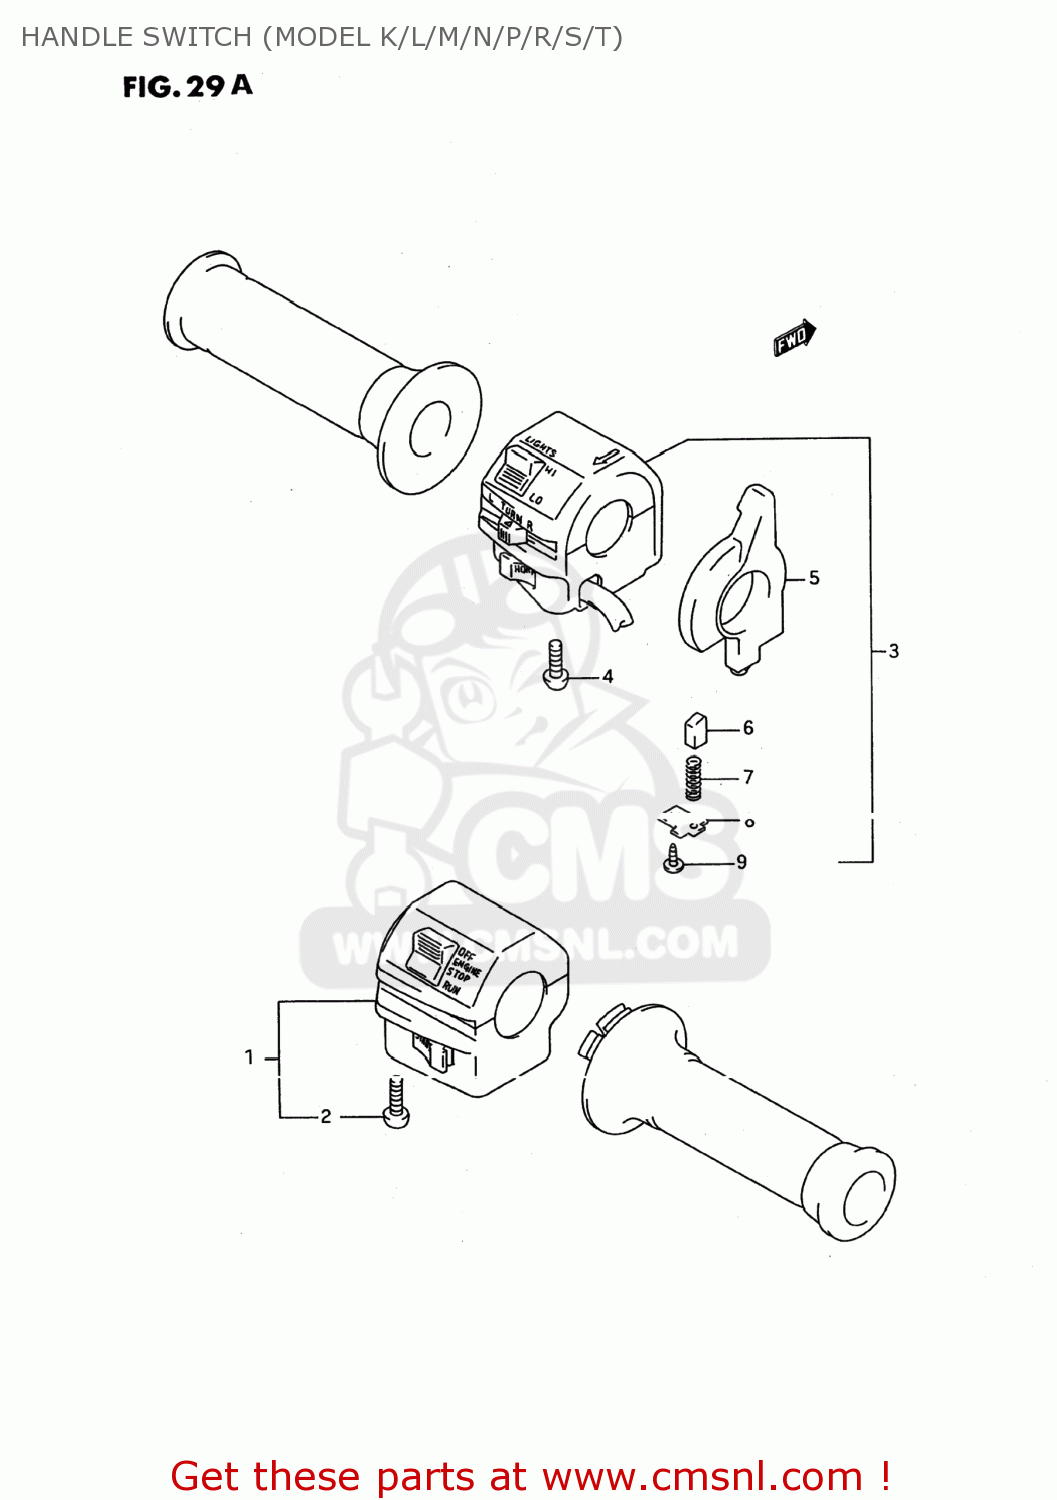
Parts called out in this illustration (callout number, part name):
1	SWITCH ASSEMBLY,HANDLE,RIGHT
2	SCREW, 5X45
3	SWITCH ASSY, HANDLE,LH
4	SCREW, 5X45
5	LEVER,CHOKE
6	PIECE,SLIDE
7	SPRING
8	PLATE
9	SCREW, TRUNK BOX
